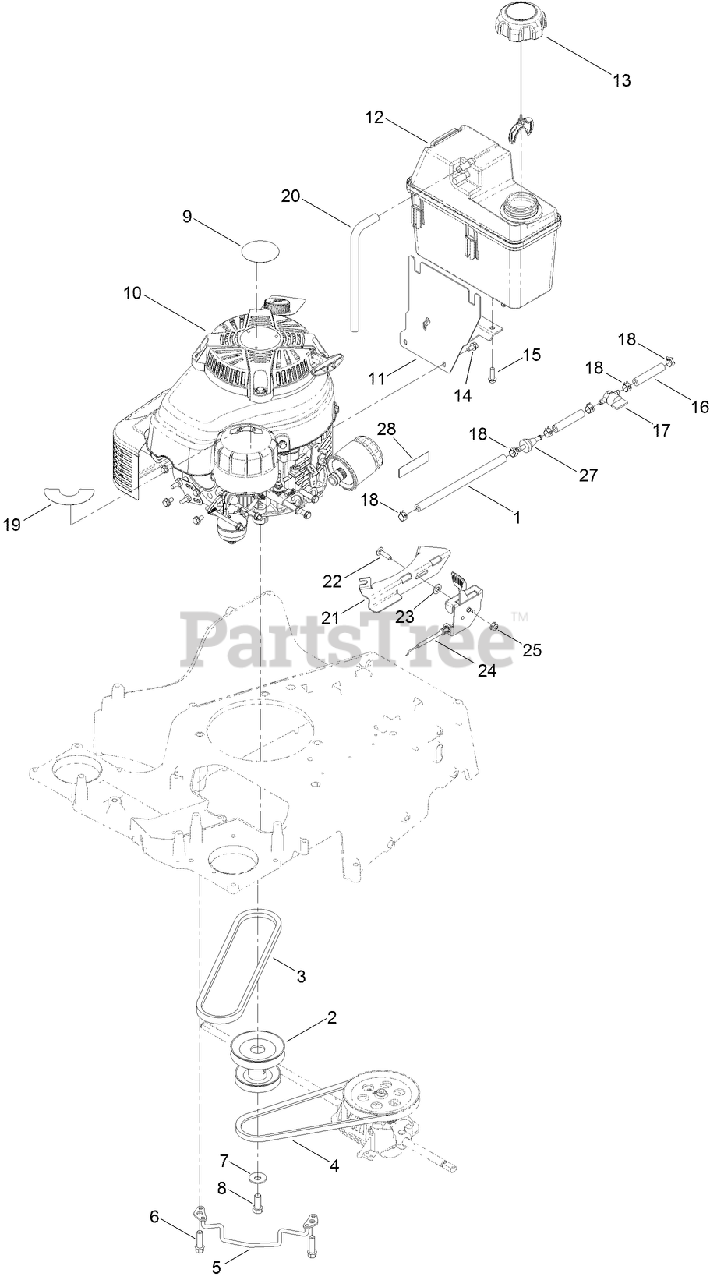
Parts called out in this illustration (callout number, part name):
1	HOSE-FUEL
2	PULLEY-ENGINE
3	V-BELT
5	GUIDE-BELT
6	SCREW-TAPTITE
7	WASHER-BELLEVILLE
8	SCREW-HH
9	Decal-Recoil
10	ENGINE-FJ180V KAW BBC
11	MOUNT-TANK
12	TANK-FUEL
13	CAP-RATCHET, TETHERED
14	SCREW-HWH
15	SCREW-HWH
16	HOSE-FUEL
17	VALVE-FUEL
18	CLAMP-HOSE
20	HOSE-VENT, CANISTER
21	BRACKET-MOUNT, THROTTLE
22	SCREW-CARR
23	WASHER-PLAIN
24	THROTTLE
25	NUT-HF
27	FILTER-FUEL
28	DECAL-WARNING, ENGINE
